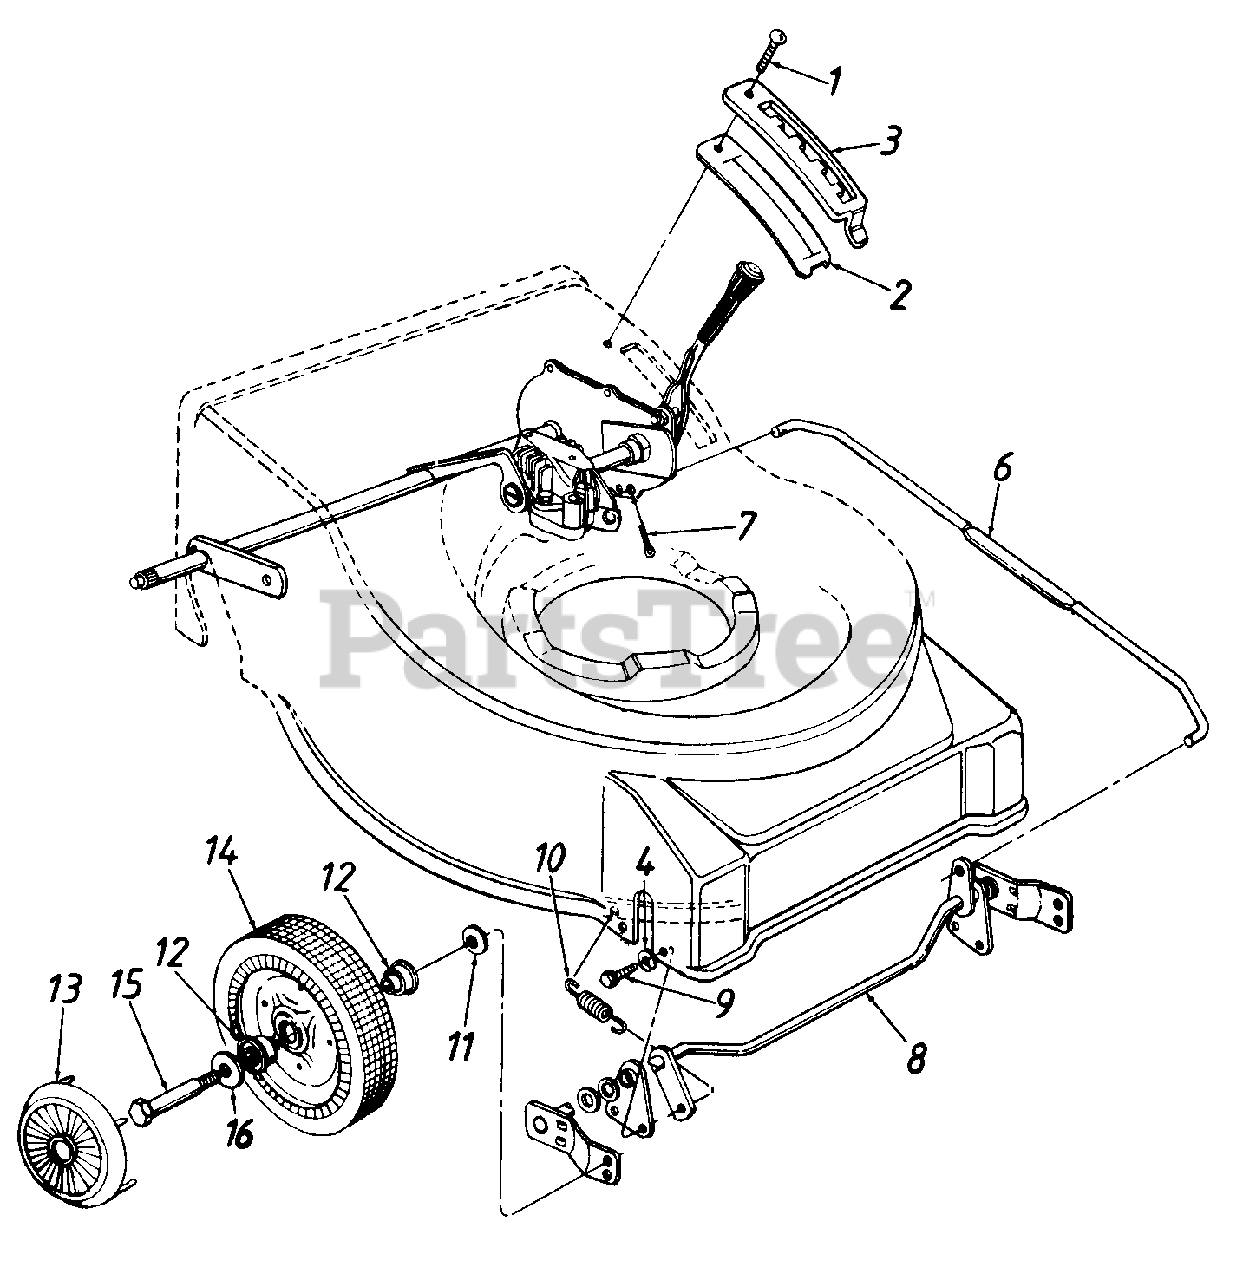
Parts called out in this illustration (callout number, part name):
1	Torx Mach. AB-Tap Scr. 1/4 x .62" Lg.
2	Height Adjustment Support
3	Height Adjustment Plate
4	L-Wash. 1/4" I.D.
6	Height Adj. Connecting Rod
7	Cotter Pin 3/32" Dia.
9	Hex L-Wash. Hd. AB-Tap Scr. 1/4 x .38" Lg.
10	Extension Spring 2 89" Lg.
11	Bell-Wash. .380" I.D. x .88" O.D.
12	Flange Ball Bearing 1/2" I.D.
13	Hub Cap
14	Wheel Ass'y. Comp.-Front
15	Shld. Bolt 498" Dia. x 1.45"
16	Fl-Wash. .531" I.D. x .93" O.D.
